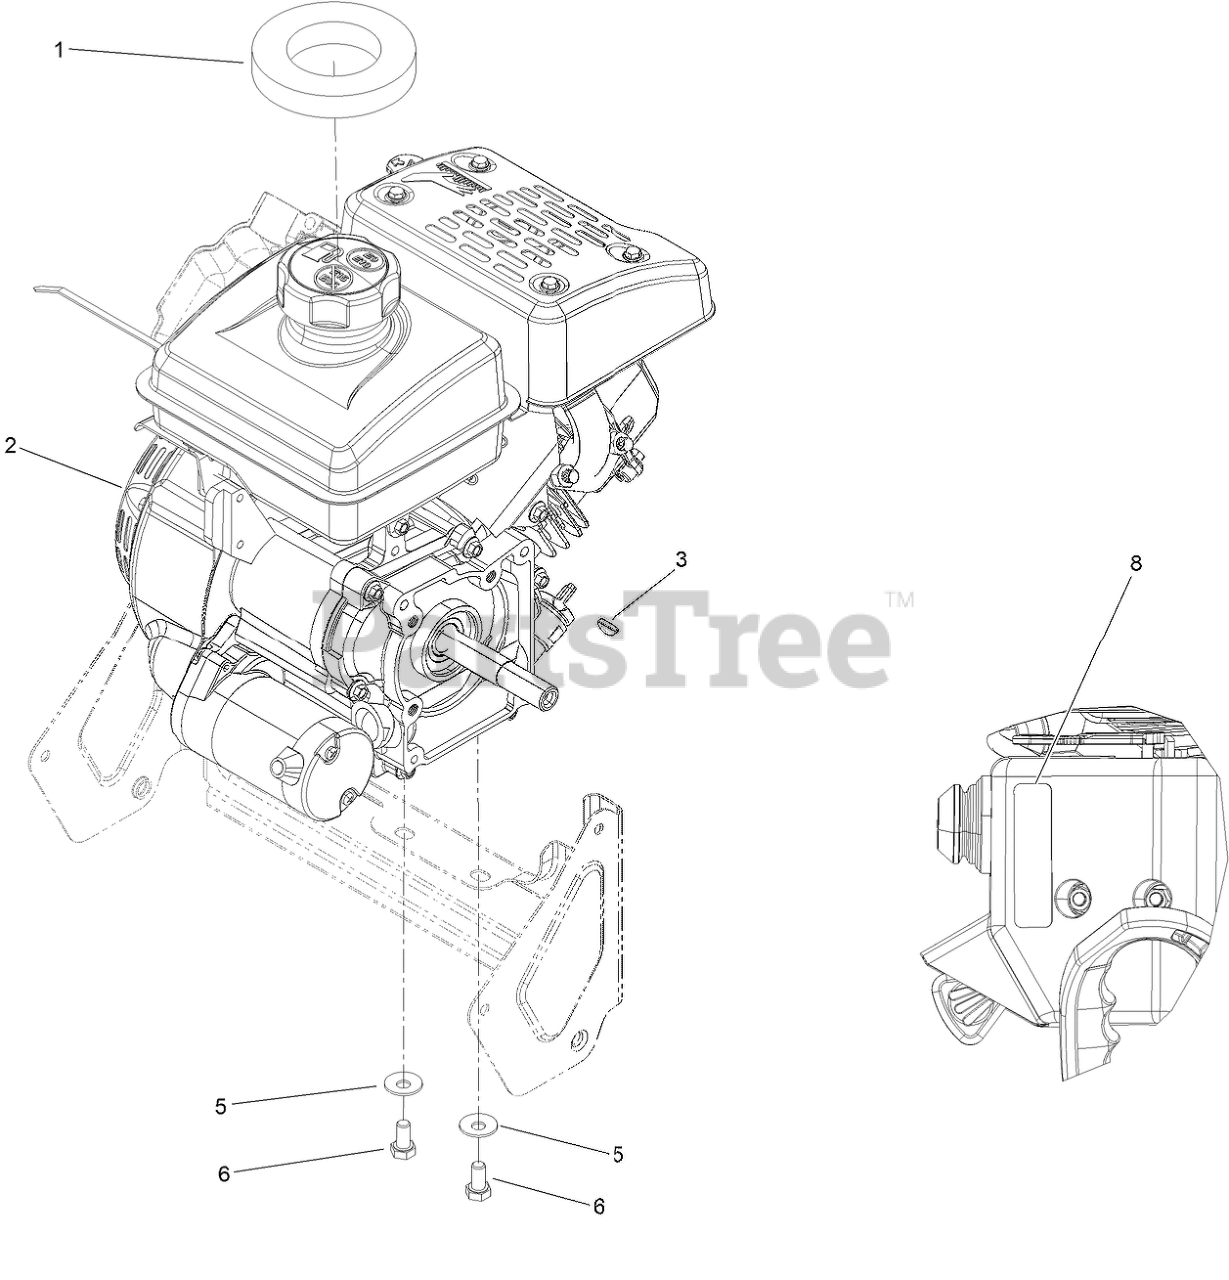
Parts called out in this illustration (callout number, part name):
1	SEAL-TANK
2	ENGINE-156FS
3	KEY-WOODRUFF
5	WASHER-BELLEVILLE
6	SCREW-HH
8	DECAL-CONTROLS, ENGINE
